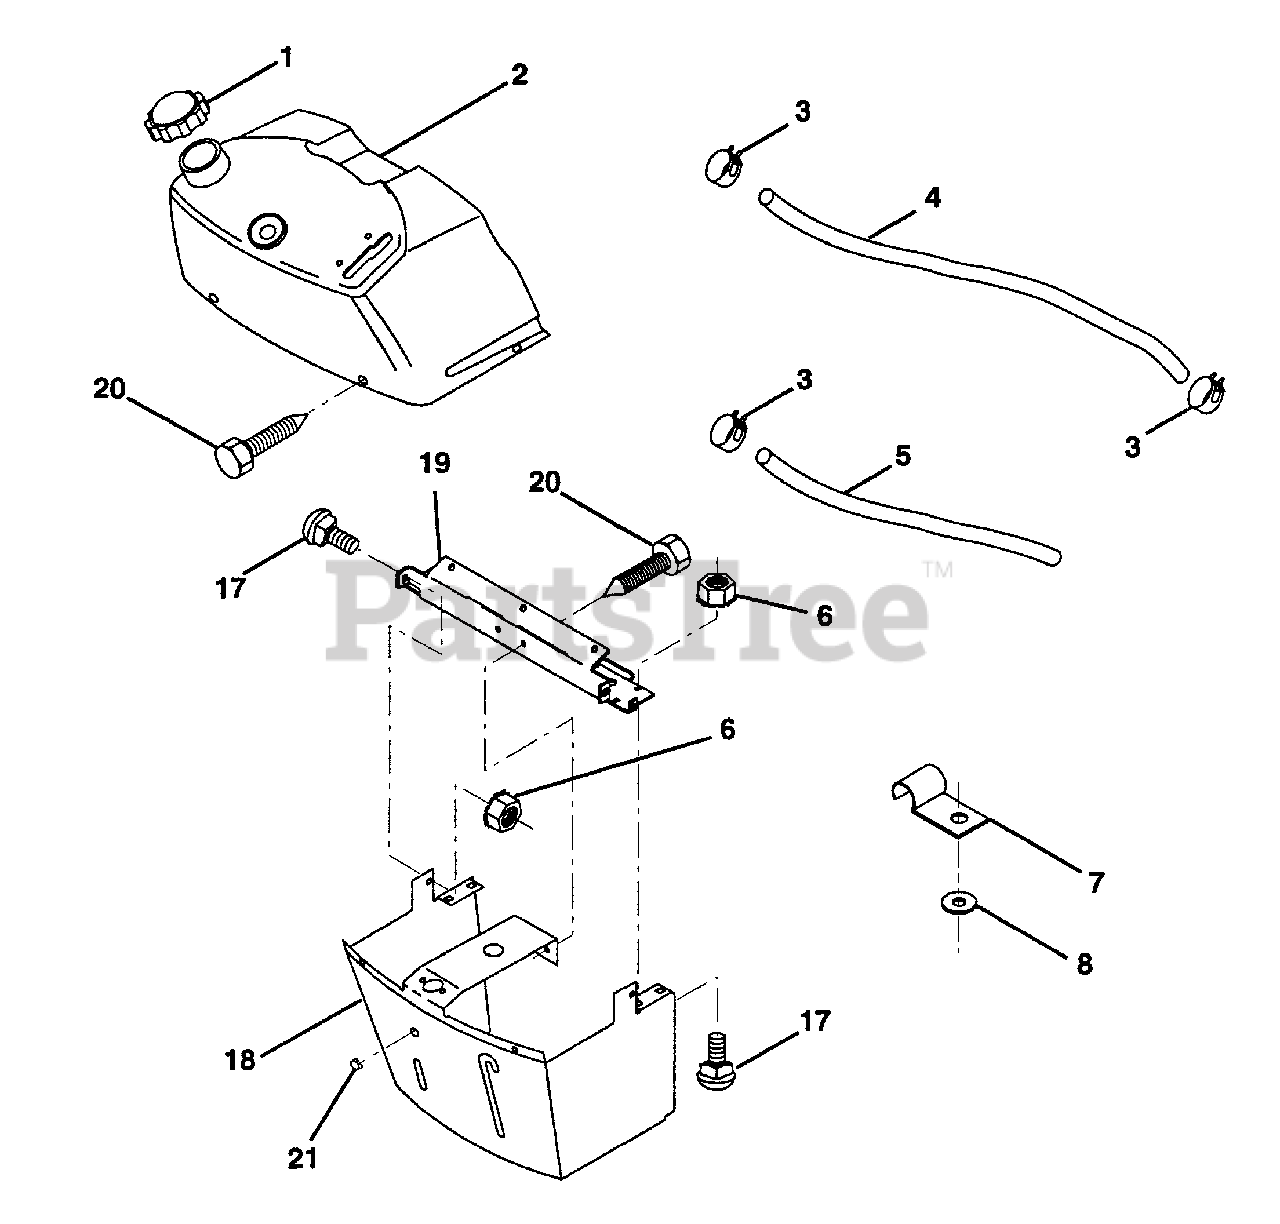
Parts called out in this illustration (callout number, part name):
1	Cap, Fuel Tank
2	Assembly, Dash & Fuel Tank
3	Clamp, Hose
4	Line, Fuel
5	Line, Fuel
6	Nut, Hex, Keps 1/4-20
7	Clip, Fuel Line
8	Washer 9/32 x 3/4 x 16 Gauge
17	Bolt, Carriage 1/4-20 x 1/2 Grade 5
18	Support Assembly, Dash
19	Brace, Cross
20	Screw, Self-Tapping 1/4-20 x 1/2
21	Plug, Dome, Black
